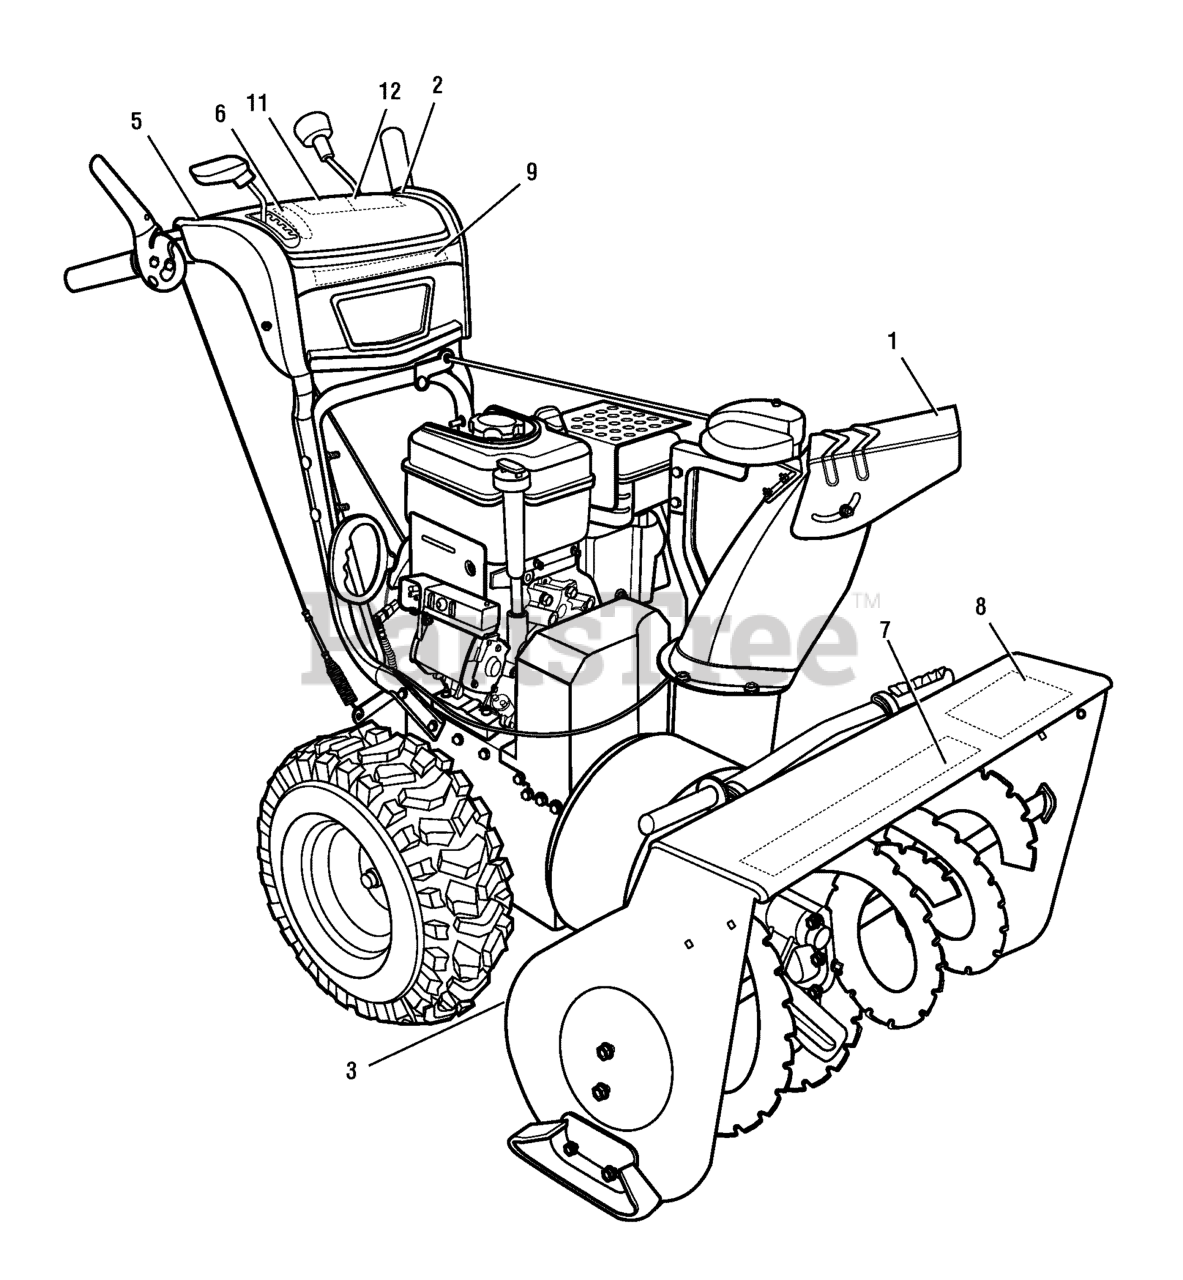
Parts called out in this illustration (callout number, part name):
1	DECAL, DANGER CHUTE
2	DECAL, DRIVE CLUTCH
3	DECAL, ISO AUGER FR/EN
5	DECAL, AUGER CLUTCH
6	DECAL, SHIFT
7	DECAL, BRUTE AUGER
8	DECAL, BRUTE AUGER HOUSING
9	DECAL, BRUTE DASH
11	DECAL, EZ STEER CONTROL
12	DECAL, CONTROLS
